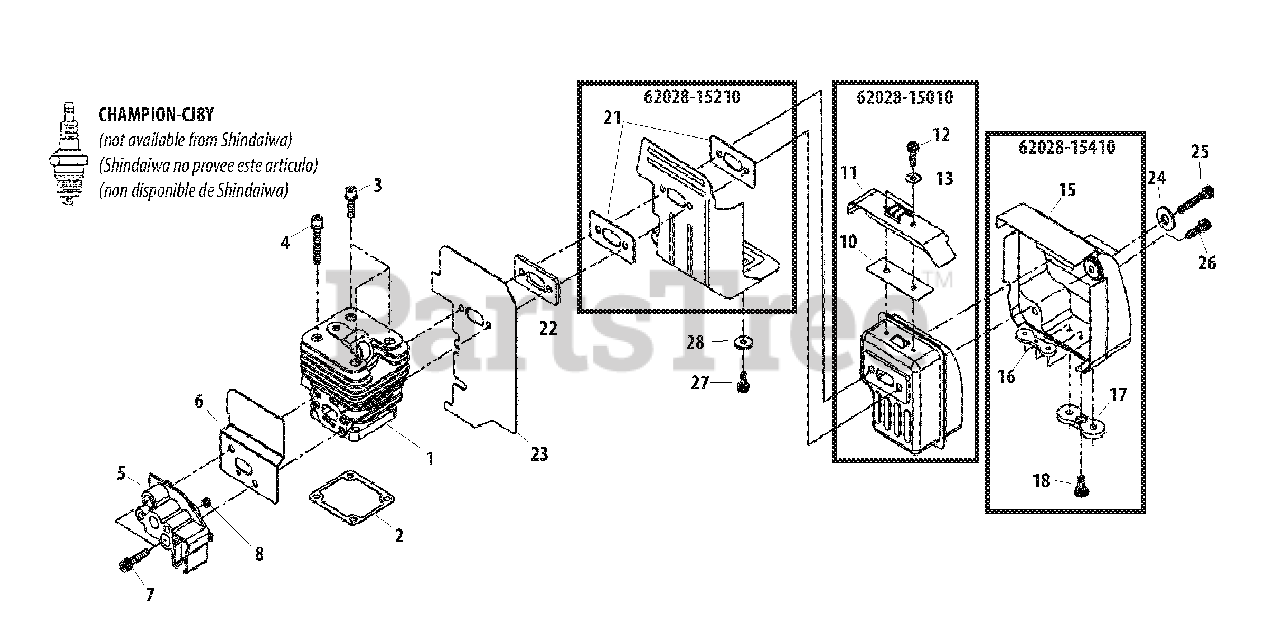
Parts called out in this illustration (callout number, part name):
1	CYLINDER
2	GASKET, CYLINDER
3	SCREW - 5X16
4	SCREW - 5X35
5	INSULATOR
6	GASKET
7	SCREW - 5X30
8	NUT
10	SCREEN, SPARK ARRESTOR
11	TAIL PLATE
12	SCREW - 4X6
13	WASHER - 4
15	COVER, MUFFLER
16	PLATE
18	SCREW - 4X8
21	GASKET
22	SPACER
23	GASKET
24	WASHER - 5
25	SCREW - 5X65
26	SCREW - 5X25
27	SCREW - 5X10
28	COLLAR
62028-15010	MUFFLER ASSY
62028-15210	GASKET, EXHAUST
62028-15410	MUFFLER COVER ASSY
